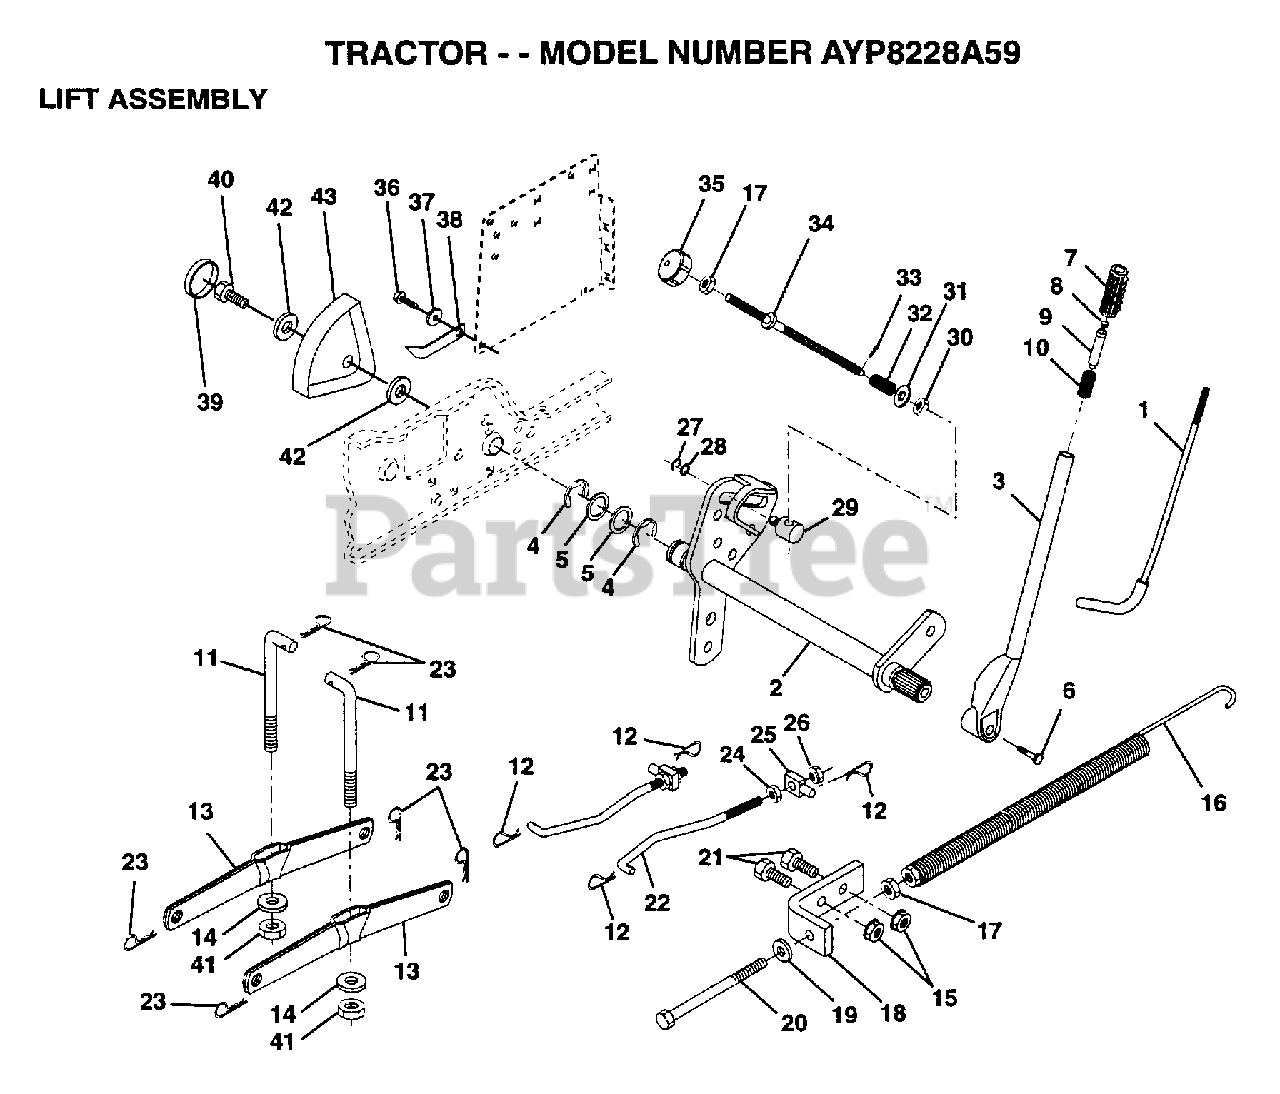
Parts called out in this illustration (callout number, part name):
1	LEVER ROD LT
2	SHAFT.LIFT.VGT.95
4	E-RING
5	WASHER
6	"BOLT,HEX"
7	GRIP HANDLE
10	SPRING T
11	LINK.LIFT.MWR.VGT
12	RETAINER.SPRING
13	ARM SUSP REAR
14	BEARING PVT LH
17	NUT
18	BRACKET SPRING AS
19	WASHER
20	BOLT-ADJ SPRING T
21	BOLT
22	LINK.FRONT
24	NUT
25	TRUNION
26	NUT.LK.W/WSH.1/2.
27	KLIP RING
28	WASHER
29	TRUNION LT
30	NUT T
31	WASHER
32	SPRING.COMP.INF.H
34	ROD.ADJ.LIFT
35	KNOB INF 3/8-16
36	SCREW
37	WASHER T
38	POINTER HGT IND
39	"PLUG,HOLE"
40	SCREW
41	NUT.CROWNLOCK.3/8
42	WASHER
43	HEIGHT INDICATOR
